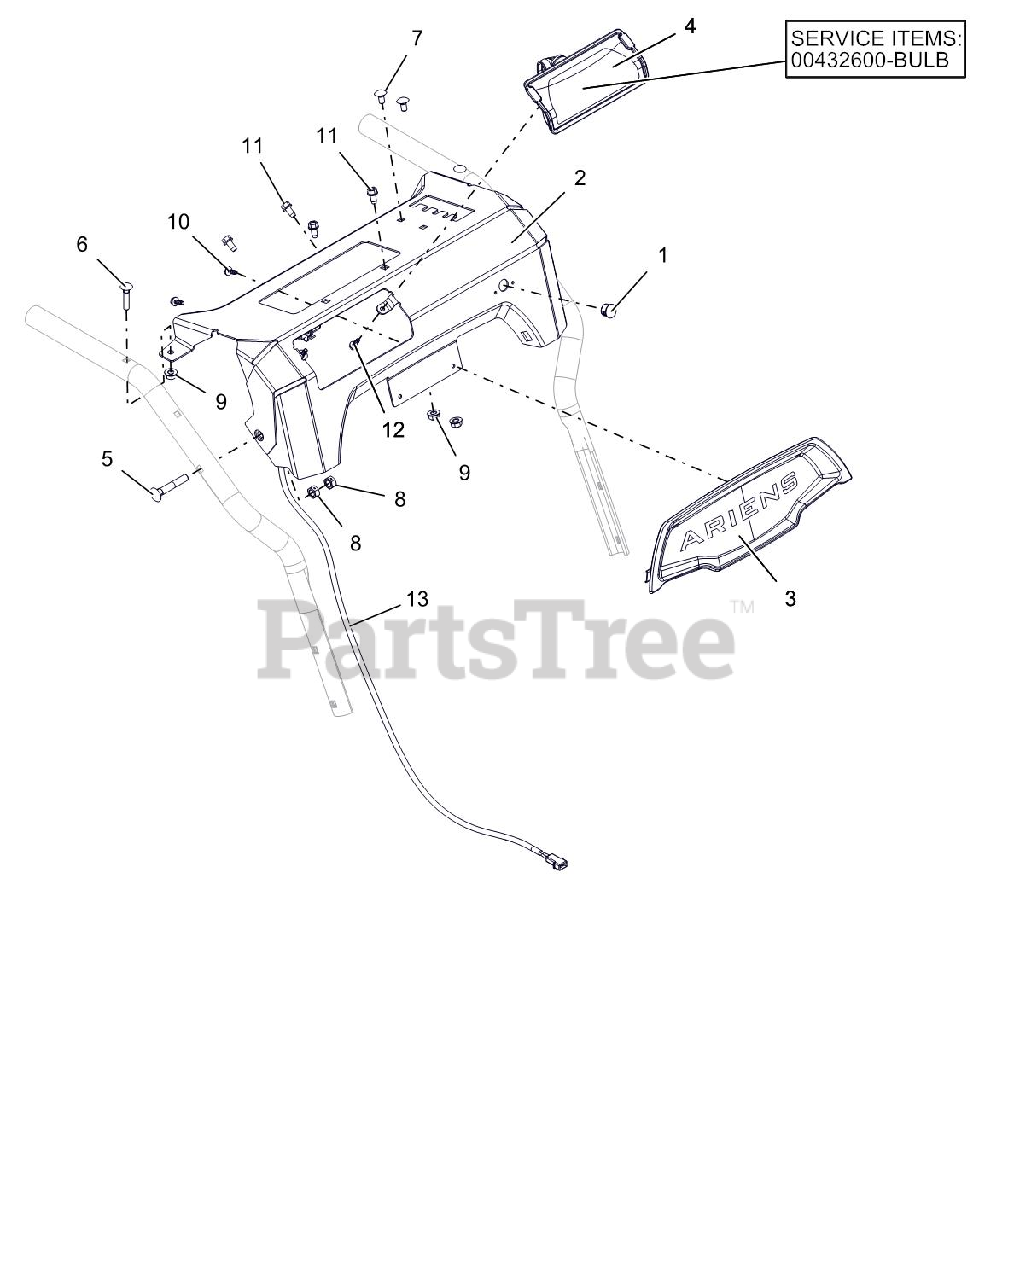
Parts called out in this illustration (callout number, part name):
1	HOLE PLUG, PLASTIC .56 HOLE
2	CTRL PANEL W/DECAL-COMP REMOTE
3	BEZEL, DASH - ARIENS SM DASH
4	BULB, LIGHT-HALOGEN 20W
4	HEADLIGHT ASY, HALO 20W 2SHOT
5	BLT-RDHDXLSQNK .31-18X2.0 G5YZ
6	BLT-RDHDXLSQNK.25-20X1.25 G5ZC
7	@BLT-RDHDSQNK .25-20X.50 G5YZ
8	@NUT-LK-CTR .31-18 YWZC
9	@NUT-LK-TOP-FLG .25-20 YWZC
10	SCR-TAP #10X.50 BOSS INDHXHD
11	SCR-TAP .25-20X.50 HWH TR YWZ
12	SCR-TAP #10X.50 BOSS INDHXHD
13	HARNESS, LIGHT - COMPACT
